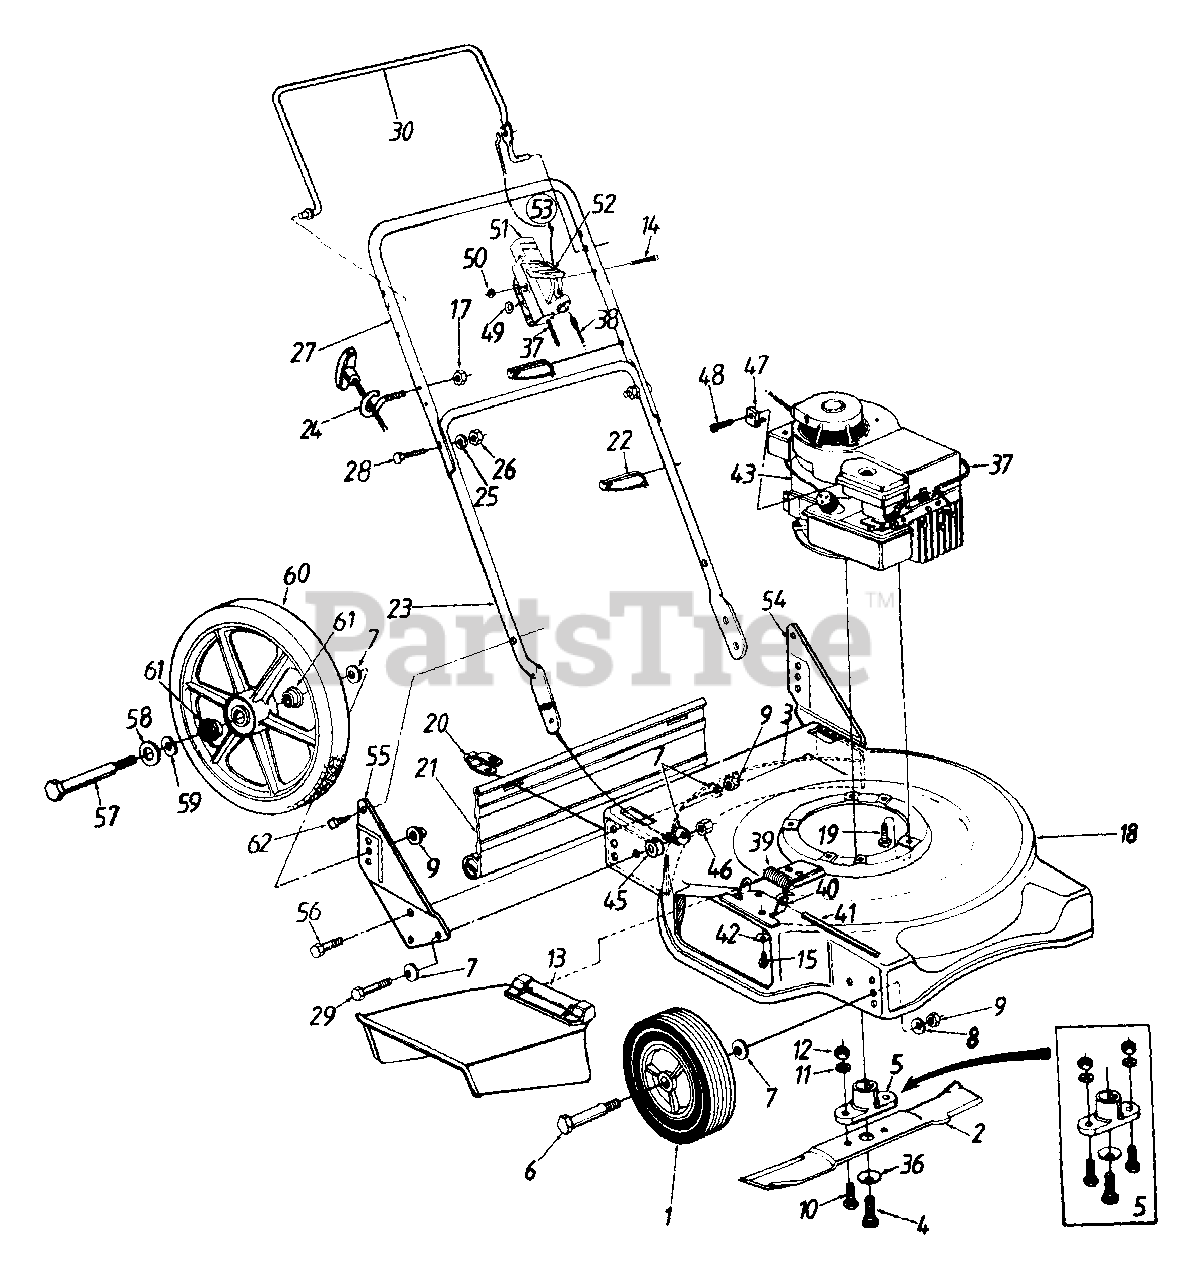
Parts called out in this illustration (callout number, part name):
1	Front Wheel Ass'y.
2	20" Blade
5	Blade Adapter Kit
6	Front Axle Bolt
7	Bell-Wash..380" I.D. x .88"
8	Bell-Wash..39" I.D. x 1.13"
9	Hex Nut 3/8-16 Thd.
10	Hex Bolt 3/8-24 x 1" Lg.
11	L-Wash. 3/8" I.D.
12	Hex Nut 3/8-24 Thd.
13	Chute Deflector Ass'y.
14	Oval C-Sunk Scr.
15	Self-Tap Scr. 1/4-20 x .5" Lg.
17	Hex L-Nut 1/4-20 Thd.
20	Hinge Clip
21	Rear Flap 16.62" Lg.
22	Cable Tie
24	Rope Guide
25	L-Wash. 5/16" I.D.
26	Hex Nut 5/16-18 Thd.
29	Hex Bolt 3/8-24 x 1.5" lg.
36	Bell-Wash..39" I.D
37	Throttle Control Wire 51"
38	Control Cable - 36"
39	Torsion Spring
40	Adapter Plate
41	Hinge Pin
42	Bell-Wash 1/4" I.D.
43	Engine
45	Spacer
46	Hex L-Nut 3/8-24 Thd.
47	Casing Clamp
48	Hex Wash Hd Scr #10-32 x .62" Lg.
49	Spring Wash. 66" I.D.
50	Hex L-Nut 1/4-20 Thd.
51	Throttle Body
52	Throttle Lever
53	Throttle Box Comp
57	Rear Axle Bolt
58	Fl-Wash 51" I.D x 1.37" O.D.
59	Spr. Wash 5" I.D. x 1" O.D.
60	Rear Wheel Ass'y
61	Flange Ball Brg. .501" I.D.
62	Hex L-Wash Hd AB-Tap Scr 1/4 x .62" Lg.
